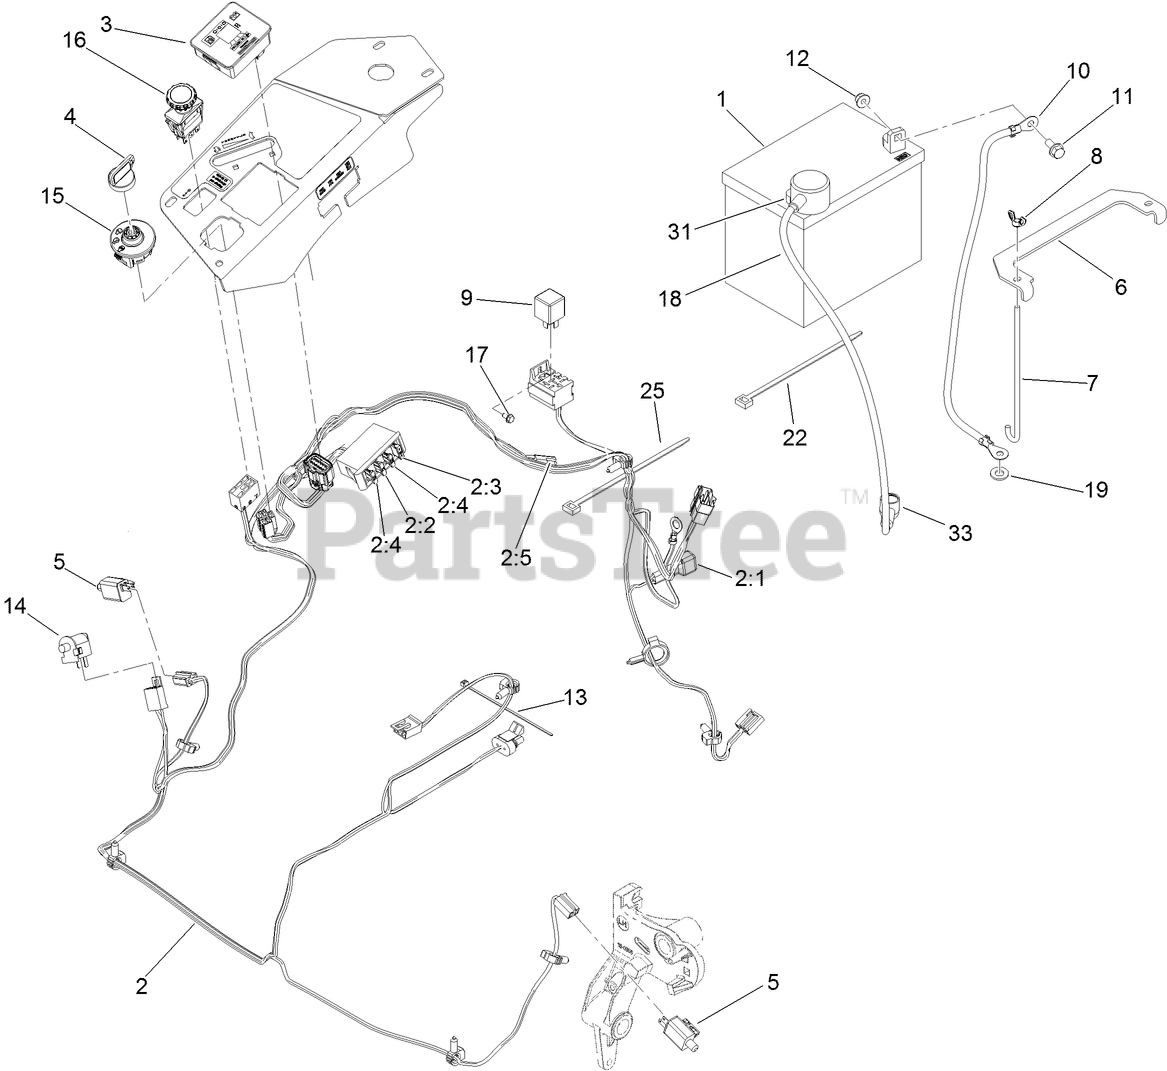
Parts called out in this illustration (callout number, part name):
1	BATTERY
2	HARNESS-WIRE, MAIN
2:2	FUSE-BLADE, 10 AMP
2:3	FUSE-BLADE, 15 AMP
2:4	FUSE-BLADE, 25 AMP
2:5	CAP-PLUG
3	FUEL/HOUR METER ASM
4	KEY-IGNITION
5	SWITCH
6	STRAP-TIE DOWN, BATTERY
7	BOLT-HOLDDOWN
8	WINGNUT
10	CABLE-BATTERY, NEGATIVE
11	SCREW-HHF
12	NUT-HF, NI
13	TIE-CABLE
14	SWITCH-BAIL
15	SWITCH-IGNITION
16	SWITCH-PTO, 10 AMP
17	SCREW-HWH
18	CABLE-BATTERY, POSITIVE
19	WASHER-FLAT
22	TIE-PLASTIC
25	TIE-PLASTIC
31	INSULATOR-BATTERY
33	INSULATOR-SOLENOID
